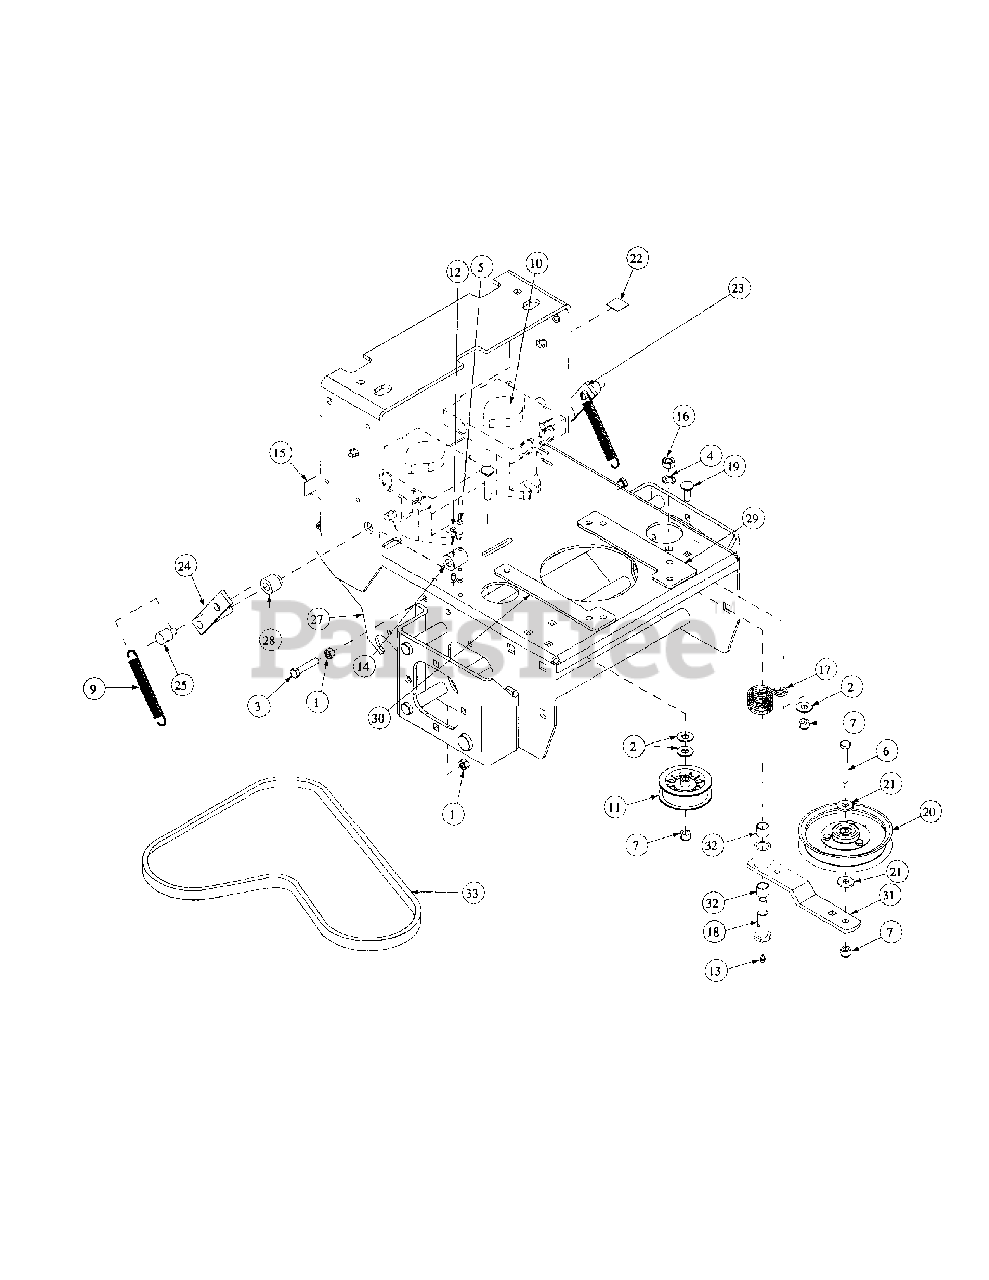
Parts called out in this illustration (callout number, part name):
1	Nut, Hex, 3/8-16
2	Flat Washer, USS 3/8
3	Cap Screw, 3/8-16 x 1-3/4"
4	Wash, Lock, 7/16, Zinc
5	Screw, CP, Square Head Set, 1/4-20
6	HHCS, 3/8-16, 1
7	Nylon Insert, Lock Nut 3/8-16
9	Wire Spring
10	Hydro Pump
11	Flat Idler Pulley with Adapter
12	Cap Screw, Square Head Set, 1/4-20
13	Grease Fitting, 1/4-28 x 3/16
14	Coupling, Trunnion
15	Decal, Made In America
16	Nut, Hex, 7/16-14
17	Spring Idler Torsion
18	Shoulder Bolt
19	Carriage Bolt, 3/8-16 x 2
20	Pulley Assembly, Idler, 5.00"
21	Flat Washer, .406 ID: 1.0 OD: .105
22	Label, Mower, Warn, Open Belt Drive
23	Hydro Pump Lever Assembly, LH
24	Hydro Pump Lever Assembly, RH
25	Pivot, Belt Tightener
27	Engine Base Assembly, Hydro WT
28	Bushing Lever Pump
29	Spacer Engine, RH
30	Spacer Engine, LH
31	Idler Arm with bearings
32	Bearing sleeves
